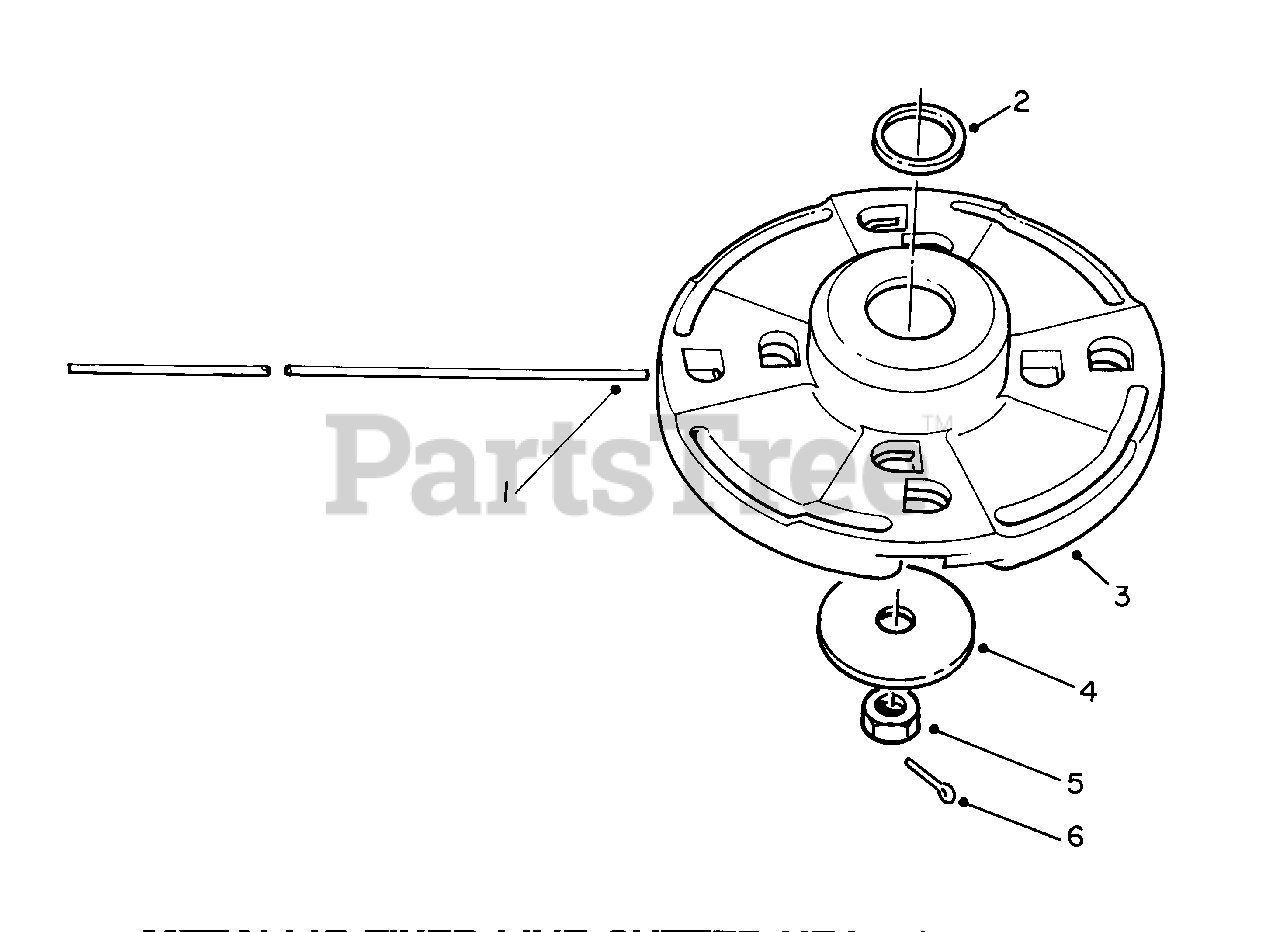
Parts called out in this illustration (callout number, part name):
1	Line-Cutting .105 Dia.
3	Head Assembly (Incl. Ref. #2)
4	Washer-Plate
5	Nut-Hex.
6	Pin-Cotter
